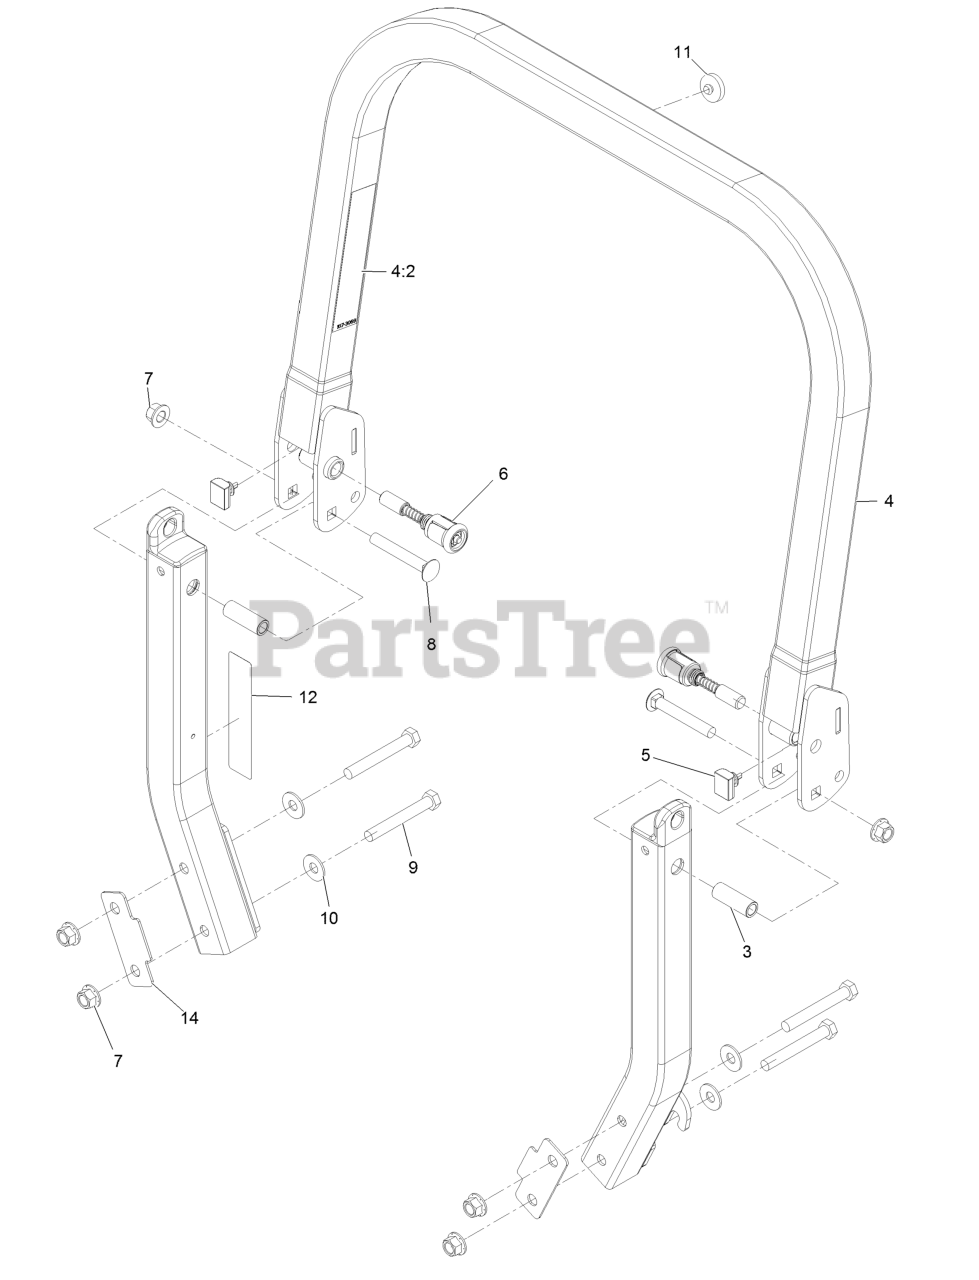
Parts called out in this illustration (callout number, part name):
4	UPPER ROPS ASM
4:2	DECAL-WARNING
5	BUMPER-ROPS
6	PIN-SPRING
7	Nut-Lock 1/2-13
8	SCREW-CARR
9	WASHER-LOCK
10	WASHER-SPRING
11	BUMPER-PUSH-IN, RUBBER
12	DECAL-CAUTION, FUEL VENT
